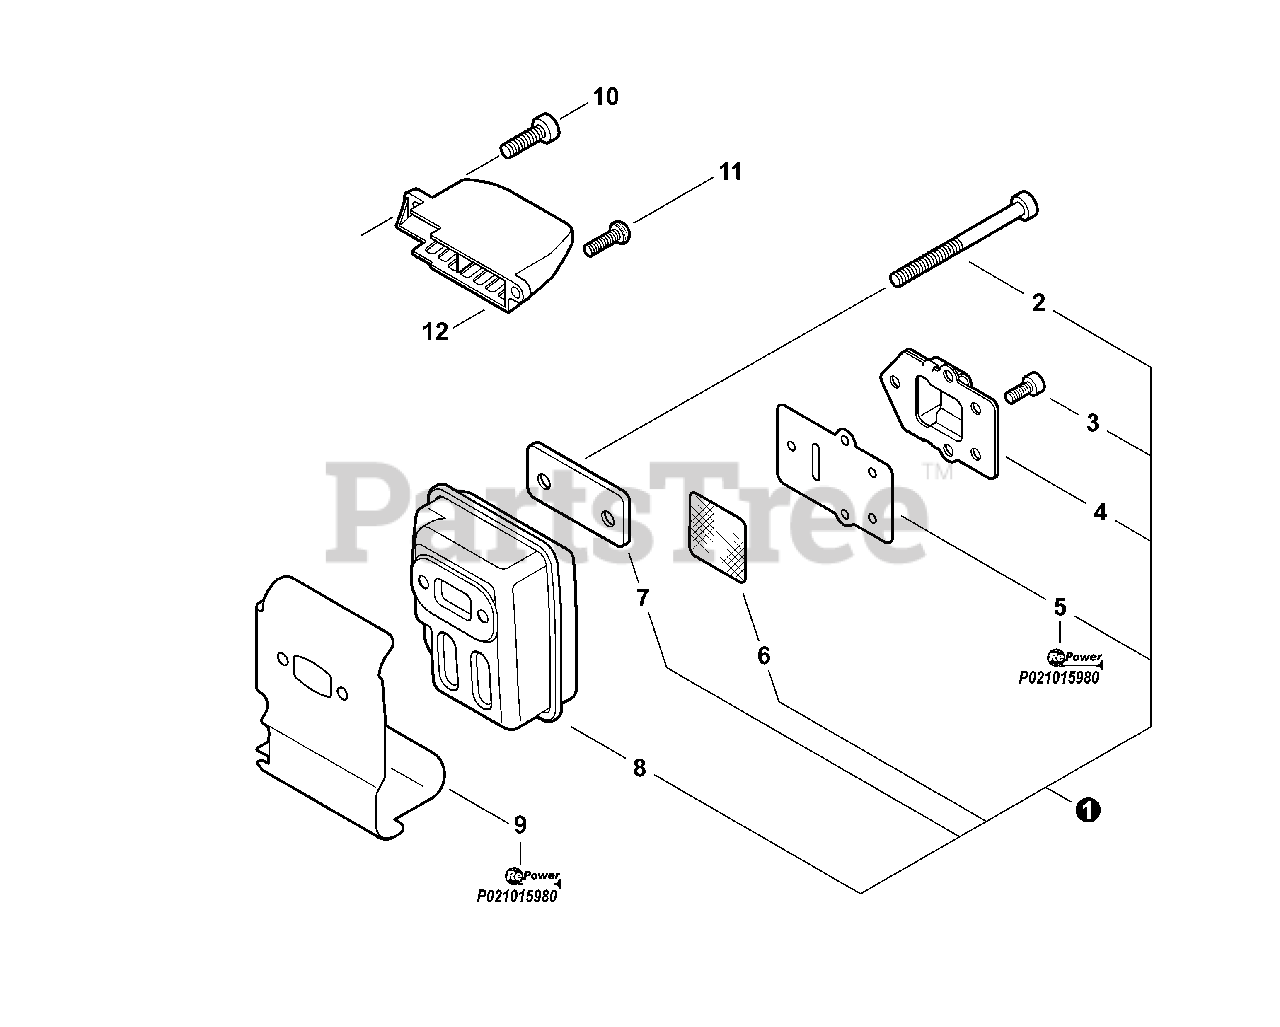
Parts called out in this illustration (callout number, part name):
1	MUFFLER ASSY
2	SCREW - 5×55
3	SCREW - 4×8 -- TORX
4	GUIDE, EXHAUST
5	GASKET, EXHAUST
6	SCREEN, SPARK ARRESTER
8	MUFFLER
9	SHIELD, EXHAUST
10	SCREW - 5×16
11	SCREW - 5×16
12	DUCT, AIR
